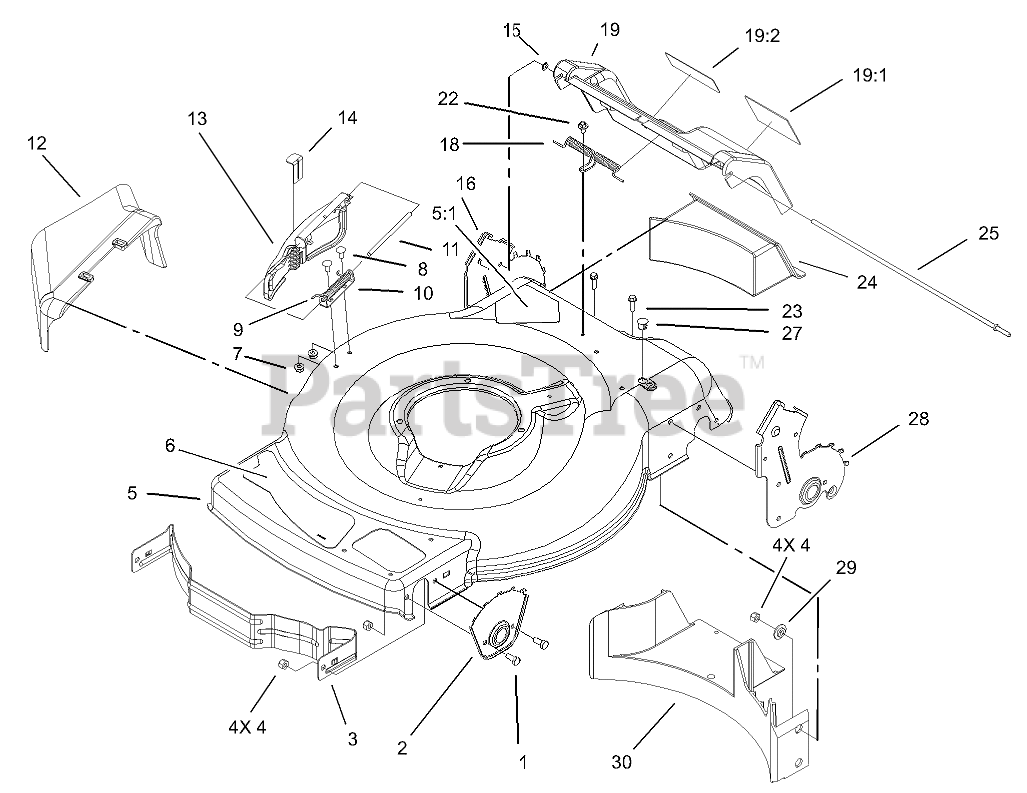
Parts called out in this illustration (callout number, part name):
1	SCREW-HH
2	Plate-HOC, Front
3	Baffle-Front
4	NUT-LOCK, NI
5	Housing (only on: 20008)
5	Housing (only on: 20009)
5:1	Decal-Danger (only on: 20008)
5:1	Decal-Danger, Cut Finger (only on: 20009)
6	Decal-Deck
7	NUT-HHF
8	SCREW-CARR
9	SPRING-TORSION
10	BRACKET-COVER
11	ROD-COVER
12	CHUTE-DISCHARGE, SIDE
13	Door-Discharge, Side
14	Lever-Latch
15	NUT-PUSH
16	RH REAR HOC PLATE ASM (only on: 20013)
18	Spring-Door, Rear
19	Door (only on: 20009)
19	Door (only on: 20008)
19:1	Decal-Warning (only on: 20009)
19:2	Decal-Warning, Door (only on: 20008)
19:2	Decal Warning (only on: 20009)
22	SCREW AND WASHER ASM
23	SCREW-HWH
24	Plug-Discharge, Rear
25	Rod-Pivot, Rear Door
27	Plug-Dome
28	LH REAR HOC PLATE ASM (only on: 20013)
29	Washer-Stepped
30	Baffle-Rear
